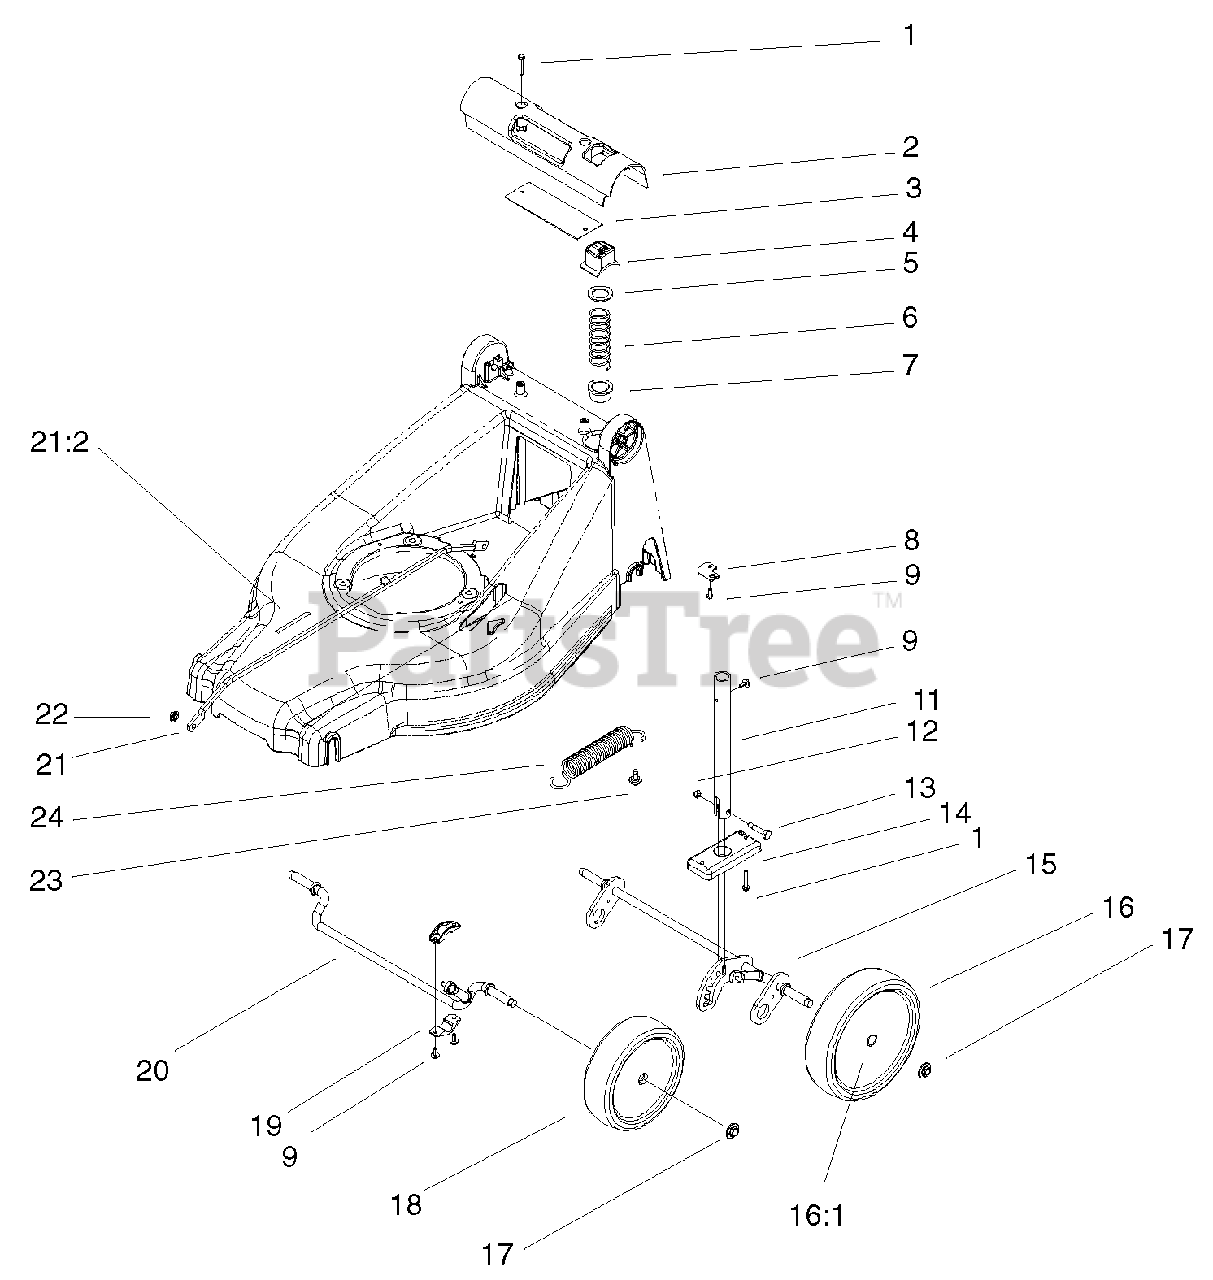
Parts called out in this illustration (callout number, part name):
1	Screw-HWH
2	Handle-Deck
3	Cover-Handle
4	Button-HOC
5	Washer-Backup
6	Spring-Compression, HOC
7	Bushing-HOC (only on: 10926)
8	Bracket-Traction Cable (only on: 10926)
9	Screw-Taptite (only on: 10926)
9	Screw-Taptite (only on: 10925)
11	Pipe-HOC
12	Nut-Lock, NI
13	Bolt-Shoulder
14	Plate-Support, HOC
15	Axle-Rear ASM
16	Wheel ASM (only on: 10926)
16	Assembly-8" Wheel (only on: 10925)
17	Nut-Lock, Flanged
18	Wheel ASM
19	Mount-Axle, Front
20	Axle-Front ASM
21	Rod-Decal ASM
21:2	Decal-HOC
23	Screw-Shoulder
24	Spring-Extension, HOC
